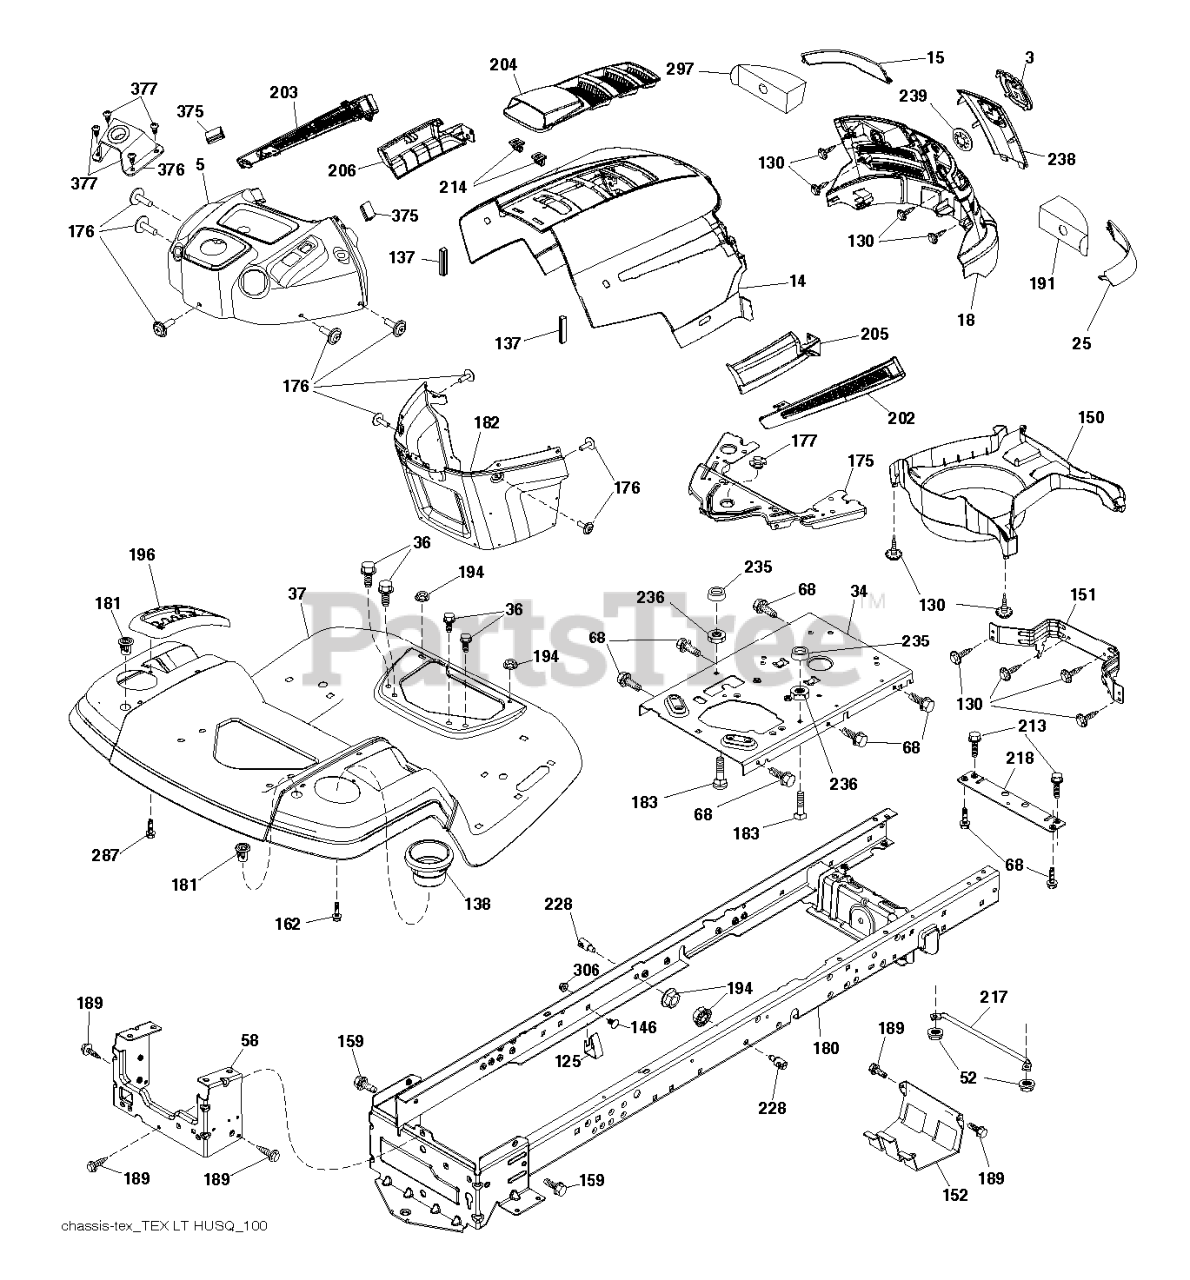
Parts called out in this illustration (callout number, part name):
1	FILTER HEAD
2	HYDRAULIC OIL FILTER
3	HYDRAULIC CAP
4	PUMP
6	OIL FILTER BRKT
7	FITTING, STRAIGHT F6400-8-8-0
8	STRAIGHT FITG
9	ELBOW, F6801-6-6-0 90 DEGREE
10	HYDRAULIC HOSE
12	TEE ASSEMBLY
13	TEE ASSEMBLY
15	NUT 9/16-18 JIC CAP
16	HCS 1/4C X 5/8
17	HCS 1/4C X 3/4 HCS
18	LOCKWASHER 1/4"
19	NUT.1/4-20.HEX.NYLOC.ZD
20	WASHER 1/4 FLAT
27	PUMP BELT
28	KEY 5 MM SQ X 25 MM
29	SCREW 5/16C X 5/8 SQ HEAD
31	NUT 3/8C WHIZ
32	NUT 3/8-16 NYLOC
33	HCS 3/8C X 2
34	IDLER ARM ASM
35	BUSHING, IDLER FLANGE
36	NUT 3/8C CENTERBLOCK
37	HCS 3/8-16 X 1 3/4 GR5
38	WASHER 3/8 FLAT
39	IDLER PULLEY
40	NUT 1/2-13 HEX NYLOC ZD
42	PIVOT BUSHING
43	IDLER ARM WLDT
44	ZERK
45	WASHER 1/2 FLAT
46	HCS 1/2C X 3 1/4
